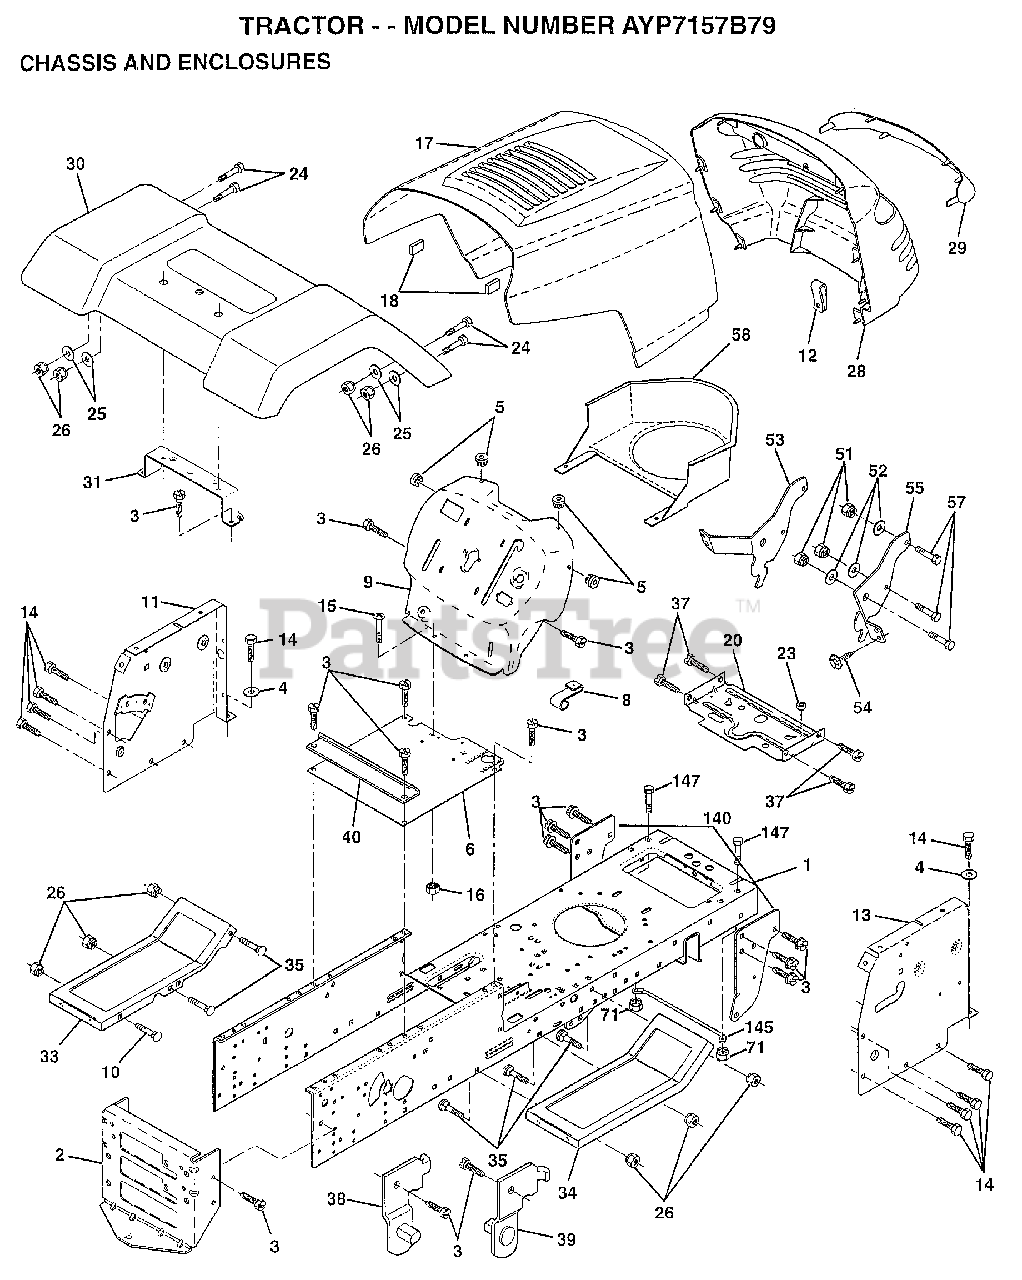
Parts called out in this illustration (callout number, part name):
1	CHASSIS ASM
3	SCREW
4	WASHER
5	BUMPER-HOOD/DASH
6	SADDLE
8	"CLIP,INSULATOR"
9	DASH SILKSCREEN
11	"PANEL-DASH,LH"
12	CLIP.TINNERMAN
13	"PANEL-DASH,RH"
14	SCREW LT
15	SCREW
17	HOOD.STL.PRV.LB
20	"PLATE-MTG,BATT/FU"
24	BOLT
25	WASHER
26	NUT
28	GRILL
29	LENS.EURO.W/DECAL
31	BRACKET SUPT FEND
33	FOOTREST.LT.LT/GT
34	FOOTREST.RH.LT/GT
35	BOLT
37	SCREW LT
38	BRACKET ASM LH
39	BRACKET ASM RH
40	SPACER FENDER LT
51	NUT
52	WASHER
53	BRACKET.GRILLE.LH
55	BRACKET.GRILLE.RH
58	AIR DUCT
140	BRKT SUSPENSION
145	"ROD POVOT,CHASSIS"
147	BOLT LT
